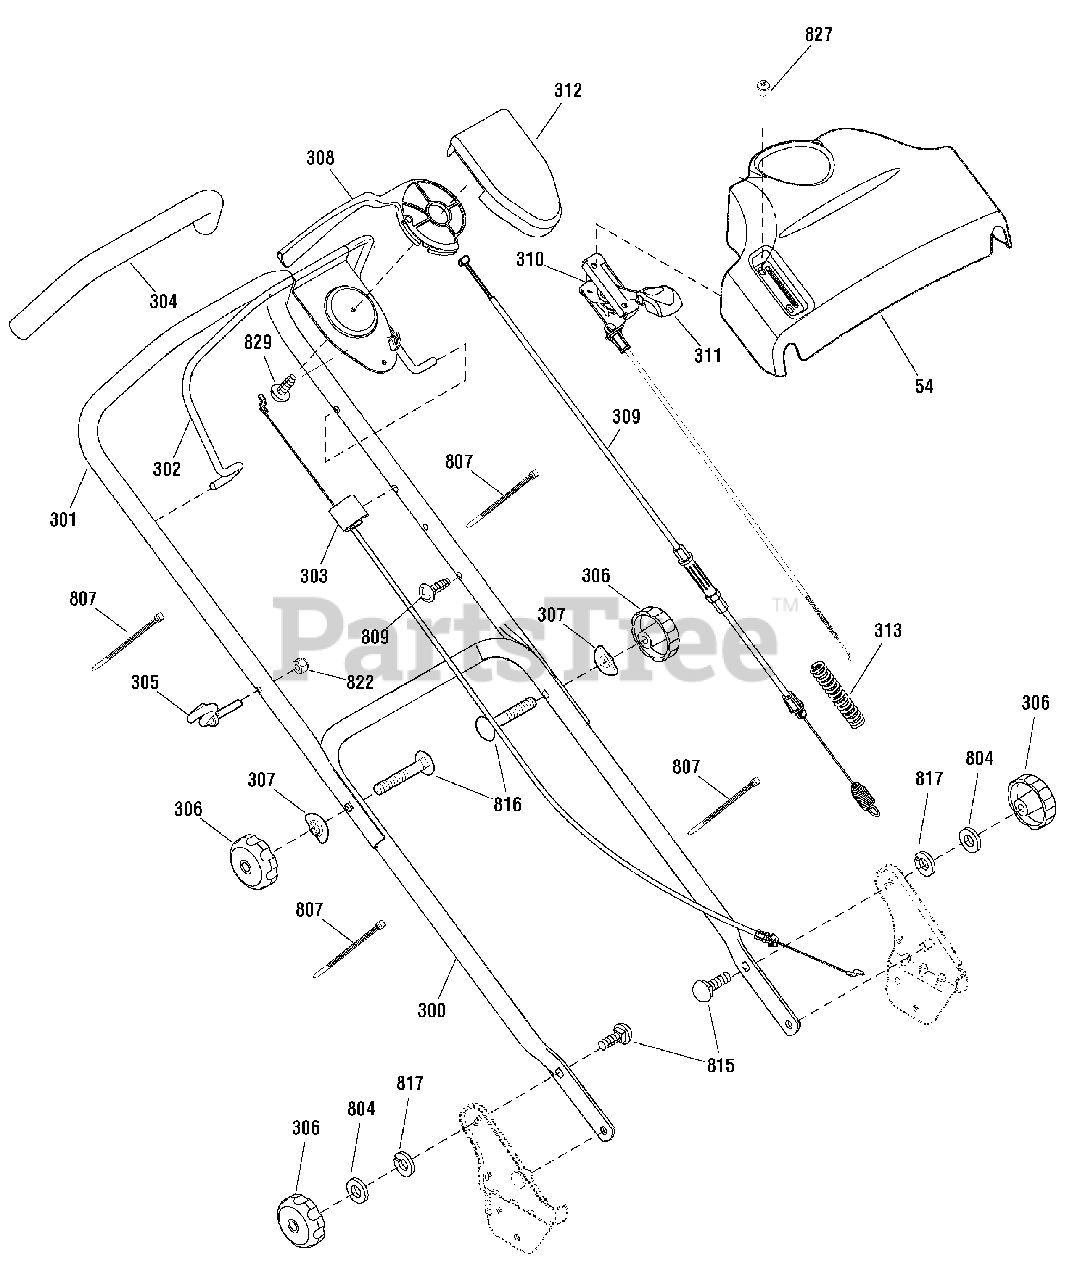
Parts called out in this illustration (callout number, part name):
54	CONTROL PANEL
300	HANDLE, Lower
301	HANDLE, Upper
302	LEVER, Engine Stop
303	CABLE, Engine Stop
304	TUBING, Foam
305	GUIDE, Rope
306	KNOB, Adjuster
307	WASHER, Formed
308	LEVER, Drive
309	CABLE ASSEMBLY, Drive
310	THROTTLE CONTROL
311	THROTTLE CONTROL
311	KNOB, Throttle Control
312	COVER, SP Control
313	SPRING, Compression
804	WASHER, 5/8
807	CABLE TIE
809	SCREW, Self Tap, #10-16 x 1/2
815	BOLT, Carriage, 5/16-18 x 1-1/8
816	BOLT, Carriage, 5/16-18 x 2
817	WASHER, Lock
822	NUT, Hex, 1/4-20
827	SCREW, 1/4-20 x 7/8
829	SCREW, Hi-Lo, #10 x 1/2
